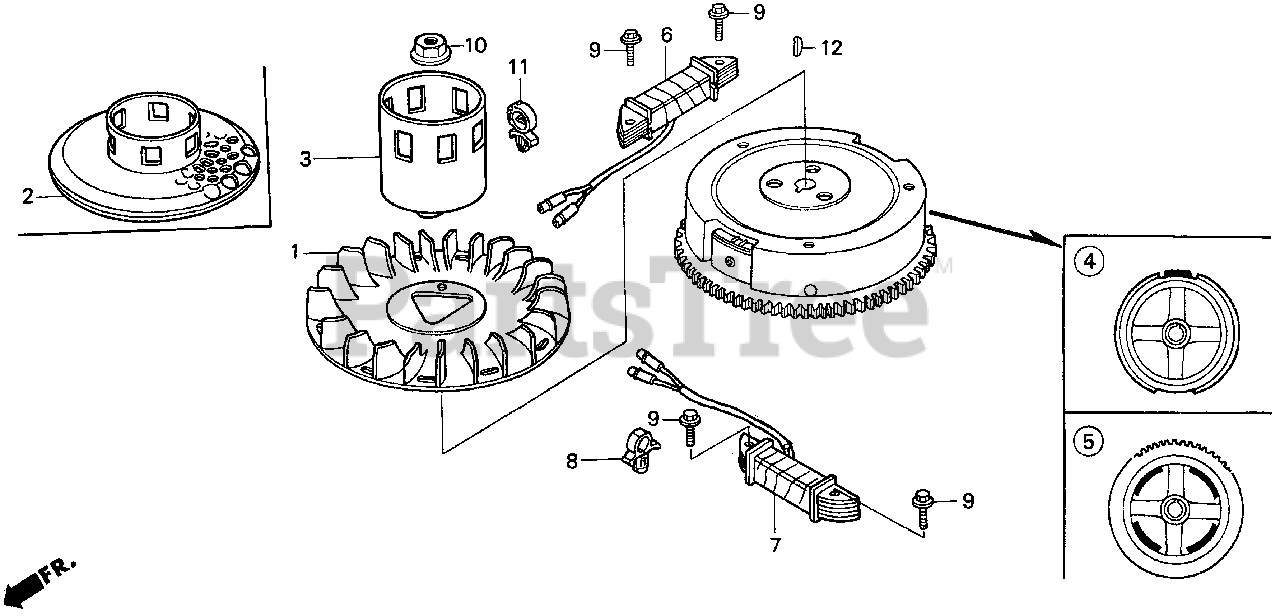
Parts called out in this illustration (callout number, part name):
1	FAN, COOLING
3	PULLEY, STARTER
5	FLYWHEEL (4 POLE)
5	FLYWHEEL
6	COIL ASSY., CHARGE
8	CLIP A, BRAKE PIPE
9	BOLT, FLANGE (6X28)
10	NUT, SPECIAL (16MM)
11	CLIP, WIRE HARNESS
12	KEY, SPECIAL WOODRUFF (25X18)
